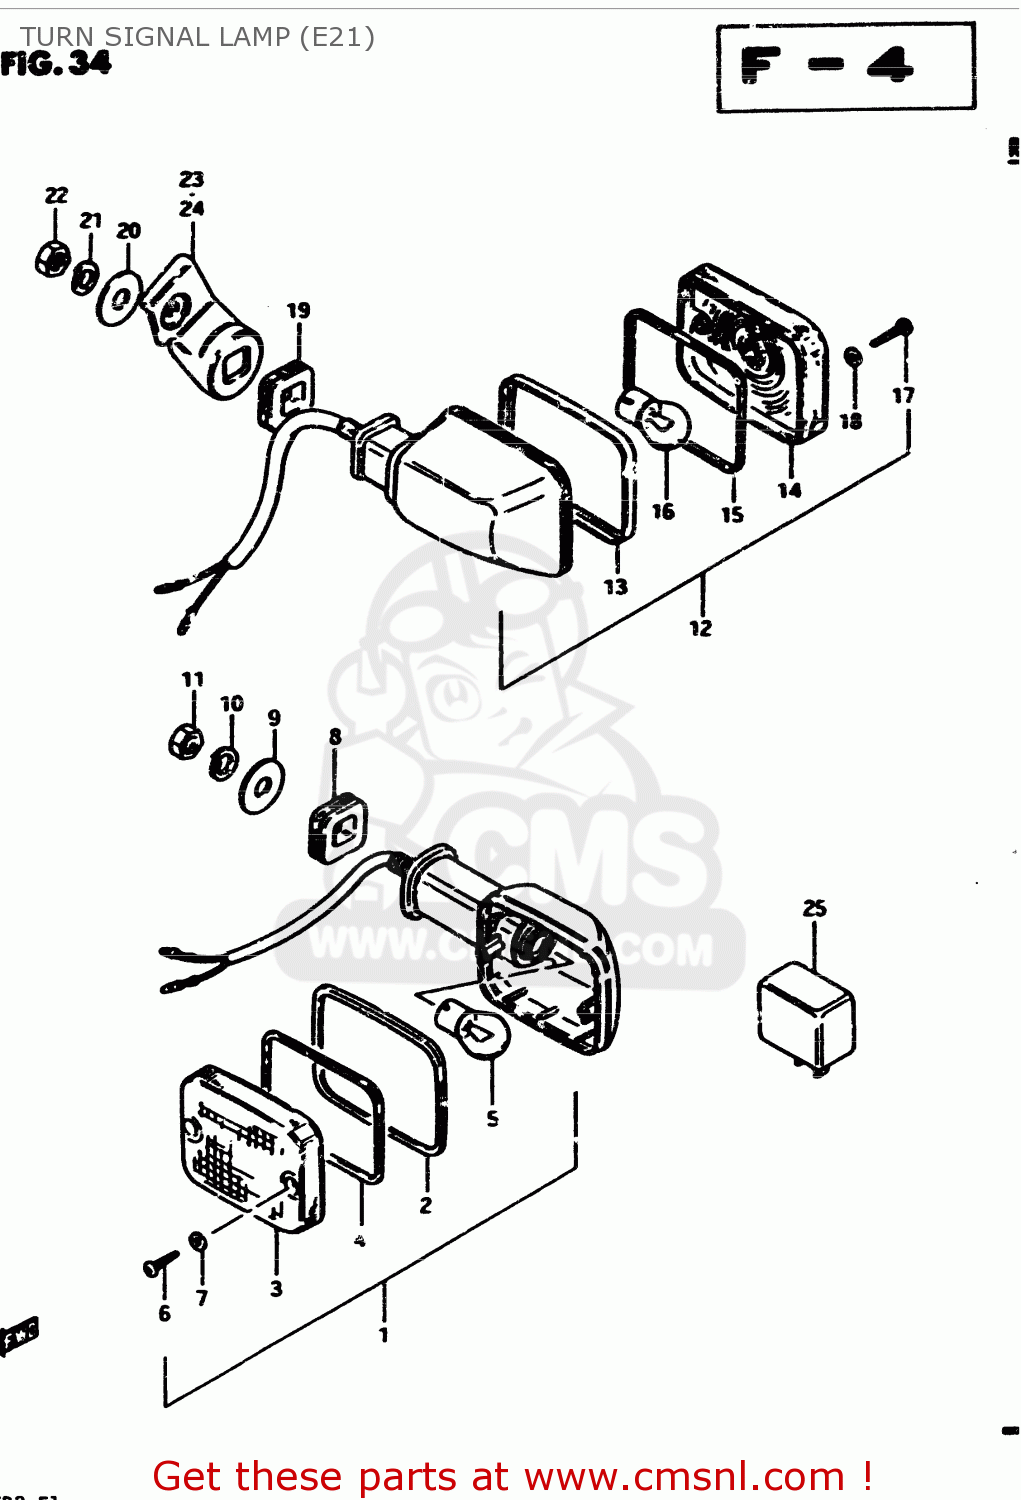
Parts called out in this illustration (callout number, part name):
1	LAMP ASSY,FR T
2	RIM
3	LENS
4	GASKET (NAS)
5	BULB(12V21W)
6	SCREW
7	GASKET (NAS)
8	CUSHION
9	WASHER (10.5X30X2.3)
10	LOCK WASHER
11	NUT
12	LAMP, REAR TURN SIGNAL
13	RIM
14	LENS
15	GASKET (NAS)
16	BULB(12V21W)
17	SCREW
18	GASKET (NAS)
19	CUSHION
20	WASHER (10.5X30X2.3)
21	LOCK WASHER
22	NUT
23	BRACKET,REAR TURN SIGNAL
24	BRACKET,REAR TURN SIGNAL
25	RELAY,TURN SIGNAL
